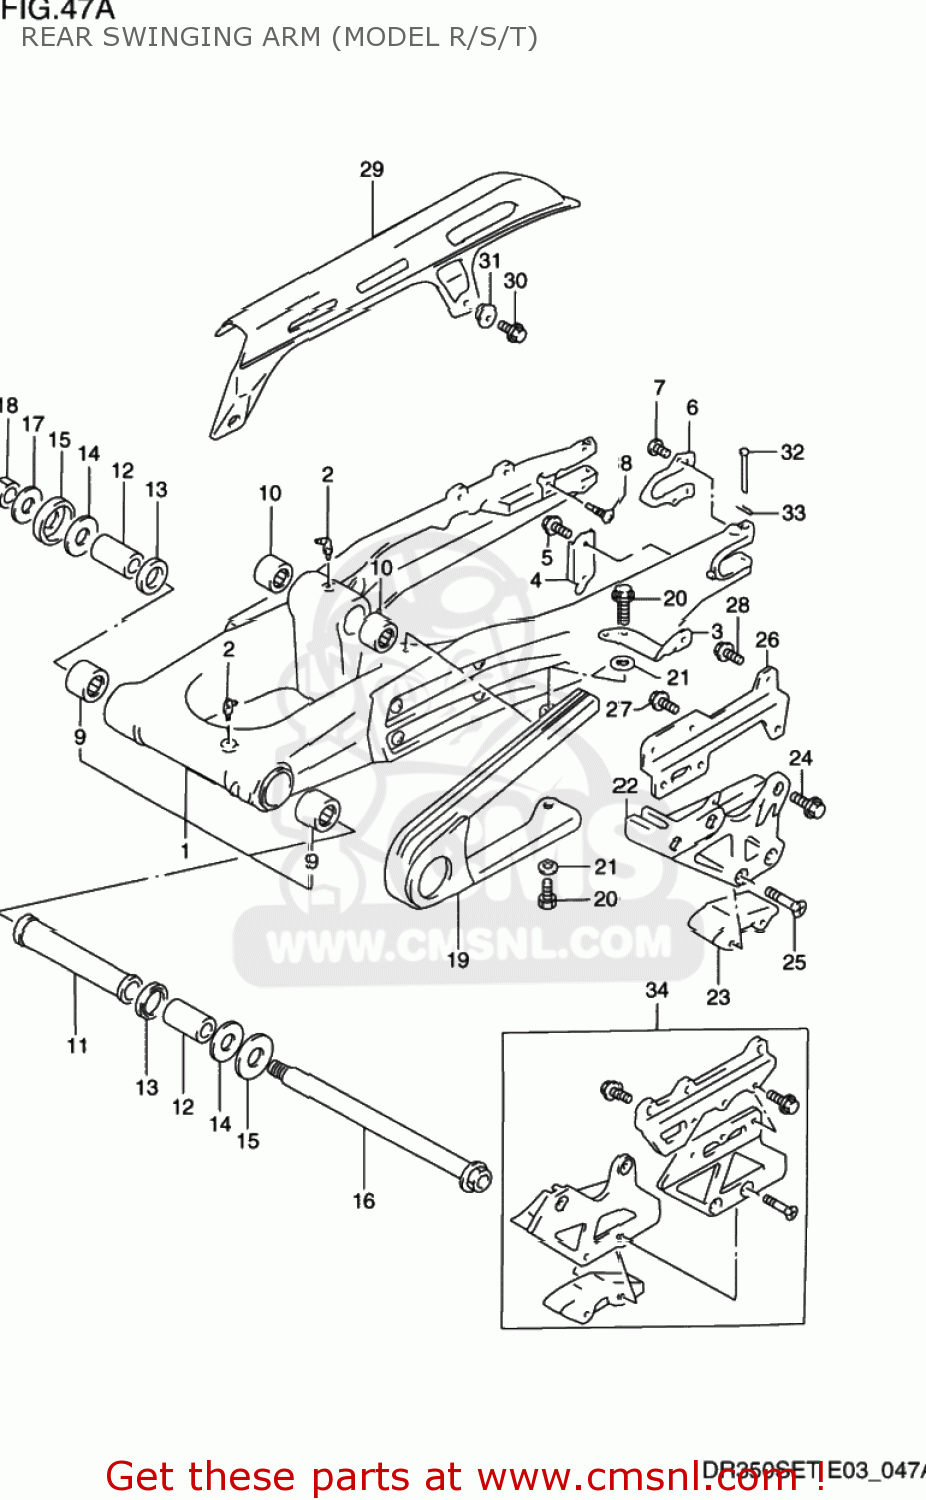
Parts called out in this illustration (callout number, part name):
1	SWINGINGARM ASSY,RR
2	NIPPLE,GREASE
3	PLATE,CHAIN CASE FTG FR
4	PLATE,CHAIN CASE FTG RR
5	BOLT
6	PLATE,SWING ARM RR
7	SCREW (5X8)
8	SCREW (M10X21)
9	BEARING(22X29X30)
10	BEARING(20X27X23.5)
11	SPACER,SWING ARM PIVOT,CENTER
12	SPACER,SWGARM PIVOT BRG
13	SEAL,OIL(22X29X4)
14	WASHER
15	COVER,SWINGINGARM PIVOT
16	SHAFT,SWINGING ARM PIVOT
17	WASHER, FIXED DRIVE FACE
18	NUT
19	BUFFER,CHAIN TOUCH DEFENSE
20	BOLT
21	WASHER
22	GUIDE,CHAIN
23	DEFENSE,CHAIN GUIDE
24	BOLT
25	SCREW
26	BRACKET,CHAIN GUIDE
27	BOLT
28	BOLT
29	CASE,CHAIN
30	BOLT
31	WASHER
32	PIN
33	CLIP
34	GUIDE SET,CHAIN
